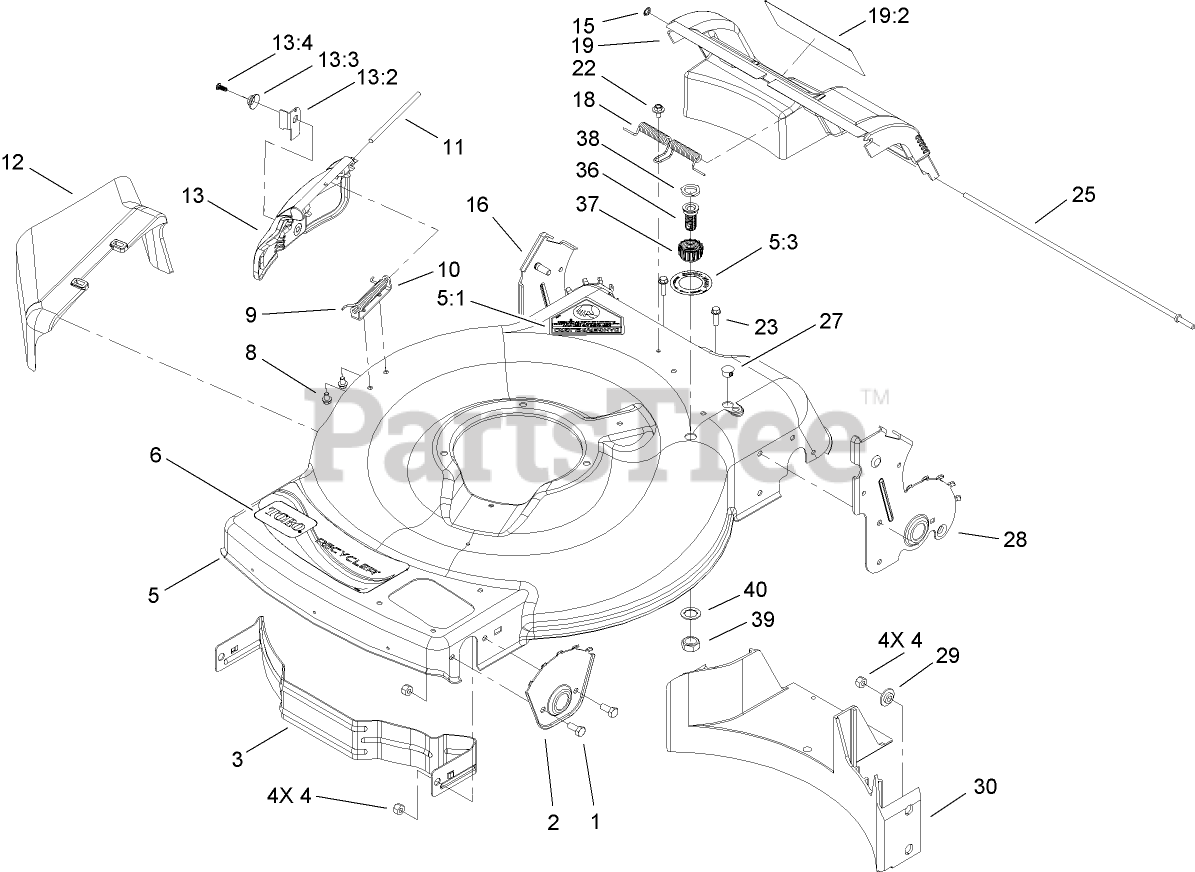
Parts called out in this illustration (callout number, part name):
1	SCREW-HH
3	BAFFLE-FRONT
4	NUT-LOCK, NI
5:1	DECAL-DANGER
5:3	DECAL-PORT, WASHOUT
6	DECAL-RECYCLER (RWD)
8	SCREW-HWH
9	SPRING-TORSION
10	BRACKET-COVER
12	CHUTE-DISCHARGE, SIDE
13	DISCHARGE DOOR ASM
13:2	LATCH-DOOR
13:3	CAP-DOOR
13:4	SCREW-PLASTITE
15	NUT-PUSH
16	8 INCH RH HOC PLATE ASM
18	SPRING-DOOR, REAR
19	REAR DOOR ASM
19:2	DECAL-WARNING
22	SCREW AND WASHER ASM
23	SCREW-HWH
25	ROD-PIVOT, REAR DOOR
27	PLUG-DOME
28	8 INCH LH HOC PLATE ASM
29	WASHER-STEPPED
30	BAFFLE-REAR
36	PORT-WASHOUT
37	COUPLING-HOSE, WASHOUT PORT
38	WASHER-SEAL, WASHOUT PORT
39	NUT-JAM
40	WASHER-LOCK
